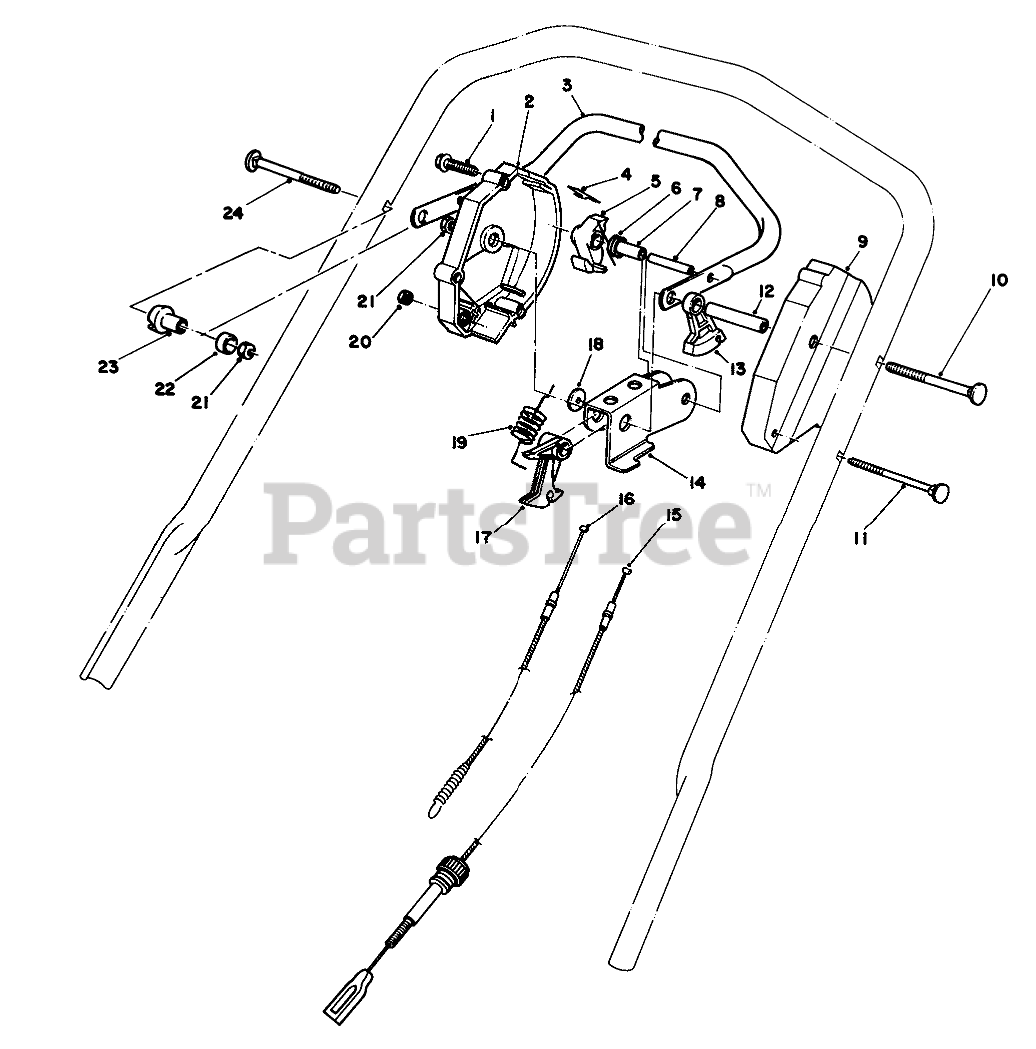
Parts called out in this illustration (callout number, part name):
1	SCREW-HWHTF
2	Housing Control R.H.
3	Bar-Control
4	SPRING-LEAF
5	HOOK-CONTROL
6	SPRING-TORSION
7	SPACER
8	PIN-ROLL, SLOTTED
9	HOUSING-CONTROL, LH
10	5/16-18 X 3 HNDLE SCREW
11	HANDLE SCREW
12	TUBING-SPACER
13	LEVER-TRACTION
14	Rocker
15	TRACTION CABLE
16	Cable-Clutch
17	LEVER-CABLE
18	PLASTIC WASHER
19	Spring-Detent
20	NUT-LOCK, NI
21	NUT-LOCK, NI
22	SPACER-NYLON
23	SPACER-SUPPORT
24	5/16-18 X 2 HNDLE SCREW
